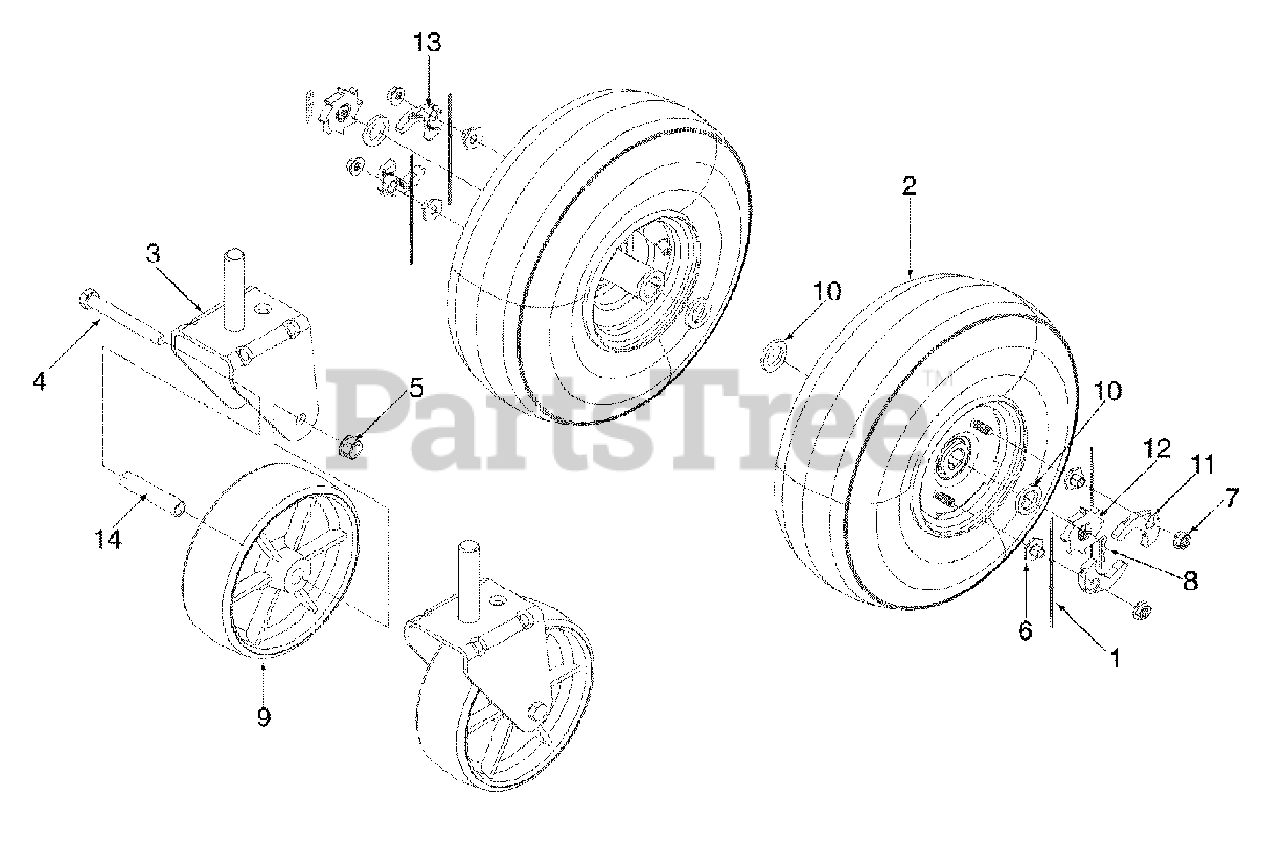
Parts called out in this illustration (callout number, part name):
1	PLASTIC RACHET SPRING
4	HEX CAP SCREW 3/8-16 x 3in
5	FLANGED LOCK NUT 3/8-16
6	HEX NUT 1/4-20
7	HEX FLANGED LOCK NUT 1/4-20
8	INTERNAL COTTER PIN .072 x 1.12 lg
9	WHEEL
10	FLAT WASHER 5/8 id 1.00 od
11	PAWL LH .345 id
12	RACHET, WHEEL 1.62 od x .5 SERR.
13	PAWL RH .345 id
14	SPACER .384 id x .500 od x 2.3
